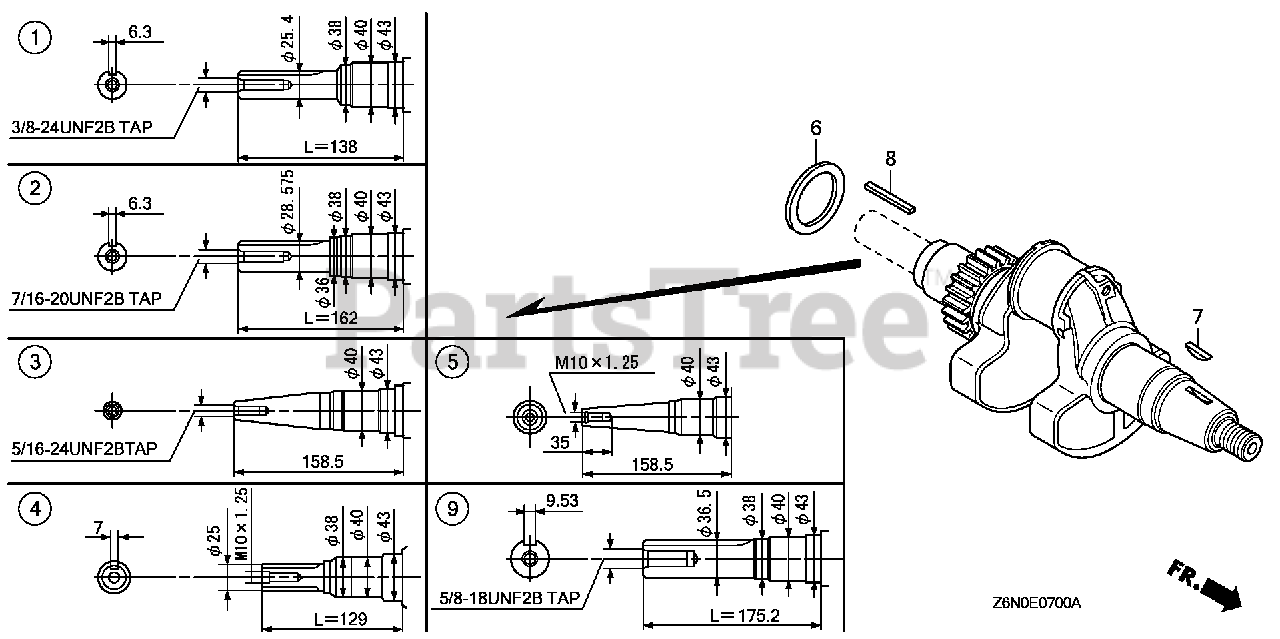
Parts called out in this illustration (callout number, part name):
1	CRANKSHAFT (L=138)
6	WASHER, CRANKSHAFT THRUST
7	KEY, SPECIAL WOODRUFF (25X18)
